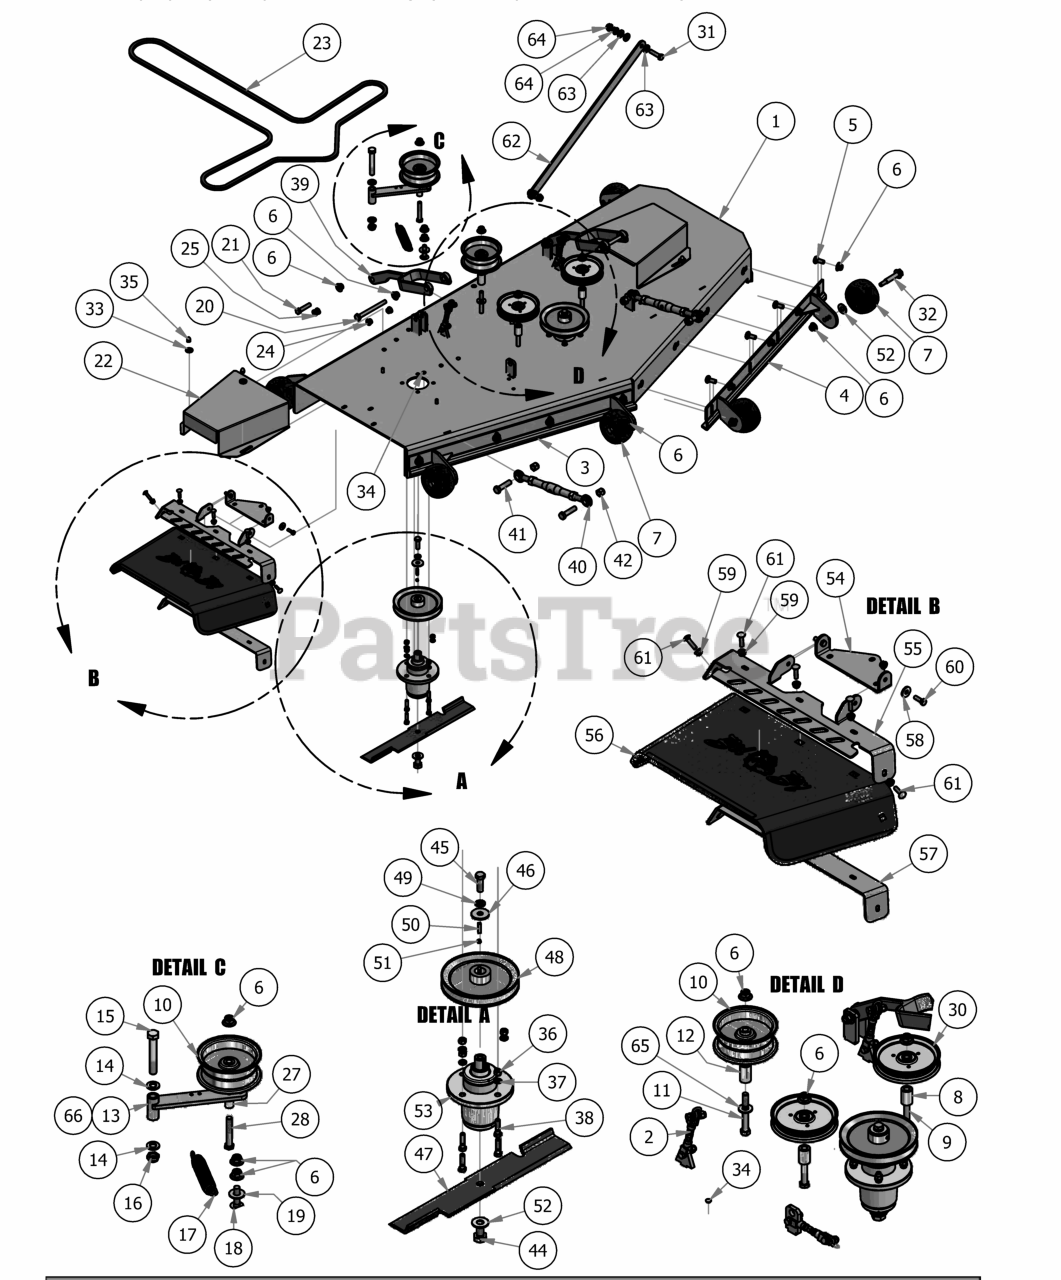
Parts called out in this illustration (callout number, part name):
1	72" ( Deck Only)
2	5- Link Adjustable Deck Hange
3	72" Deck Adustable Front (Right)
4	72" Deck Adjustable Front (Left)
5	1/2" x 1 1/4 Carriage Bolt
6	1/2-13 Nylon Insert Flange Nut
7	Anti-Scalp Roller
8	Idler Pulley Standoff
9	1/2 x 3 1/2 Flange Bolt Grade 8
10	5 3/4" Deck Idler Pulley
11	1/2" x 4" Bolt (Grade 8)
12	1 3/4" Pulley Spacer
13	Deck Idler
14	.630 ID Plastic Washer
15	5/8" x 4" Hex Bolt
16	5/8-11 Nylon Insert Jam Half Nut
17	Deck Idler Spring
18	1/2 x 2" Carriage Bolt
19	.517 Square Hole Round Washer
20	1/2" x 5 1/2" Bolt
21	1/2-13X 2-1/4 GR Hex Bolts
22	72 Outlaw Spindle Pulley Cover
23	B252-50 Fits 2007 72" Diesel
24	Flange Bushing For Upper Deck Arm
25	Flange Bushing For Lower Deck Arm
26	Double Bearing For Spindle
27	Spacer 3/4 OD x 1/2 ID x 3\4 Length
28	1/2-13 x GR 5 Hex Bolt Zinc
29	Roller Support Tab Adjustable
30	5-3/4 Idler Pulley-Capitol Stampings
31	1/2-13x2 Grade 8 Hex Bolt
32	Deck Wheel Bolt
33	.360 ID Plastic Washer-Black
34	Black, Round Stick-On Rubber Bumper
35	Acorn nut-pulley Cover
36	3/8" Hex Nut
37	3/8" Lock Washer
38	3/8" x 1 1/2" Hex Bolt
39	Deck Arm Assembly
40	Turnbuckle (Top Link)
41	5/8" x 2 1/2" Grade 5 Hex Bolt (Coarse)
42	5/8 Std NC Nylock Nut
43	Turnbuckle Bracket (deck)
44	5/8" x 1 1/2" Grade 8 Hex Bolt (Fine)
45	1/2"-20 x 1 1/2 - Grade 5 Fine Thread Bolt
46	1/2 Belleville Washer
47	72" High Lift Fusion Blade
48	7" Deck Pulley
49	1/2" Lock Washer
50	1/4" x 1" Key
51	5/16 Set Screw
52	5/8'' Flat Washer
53	OUTLAW SPINDLE ASSEMBLY
54	Discharge Chute Hanger (deck mounted)
55	60" Discharge Chute Upper Hanger
56	Rubber Discharge Chute
57	60" Discharge Lower Bracket
58	.360 ID Plastic Washer
59	5/16-18 Nylon Flange Nut
60	5/16" x 1" Bolt
61	5/16" x 1 1/4" Carriage Bolt
62	Panhard Linkage Bar
63	.505 Nylon Spacer
64	1/2" Flange Nut
65	1/2" Washer (Grade 8)
66	Deck Idler Complete Assembly- Componets 6,10,13,27,28
